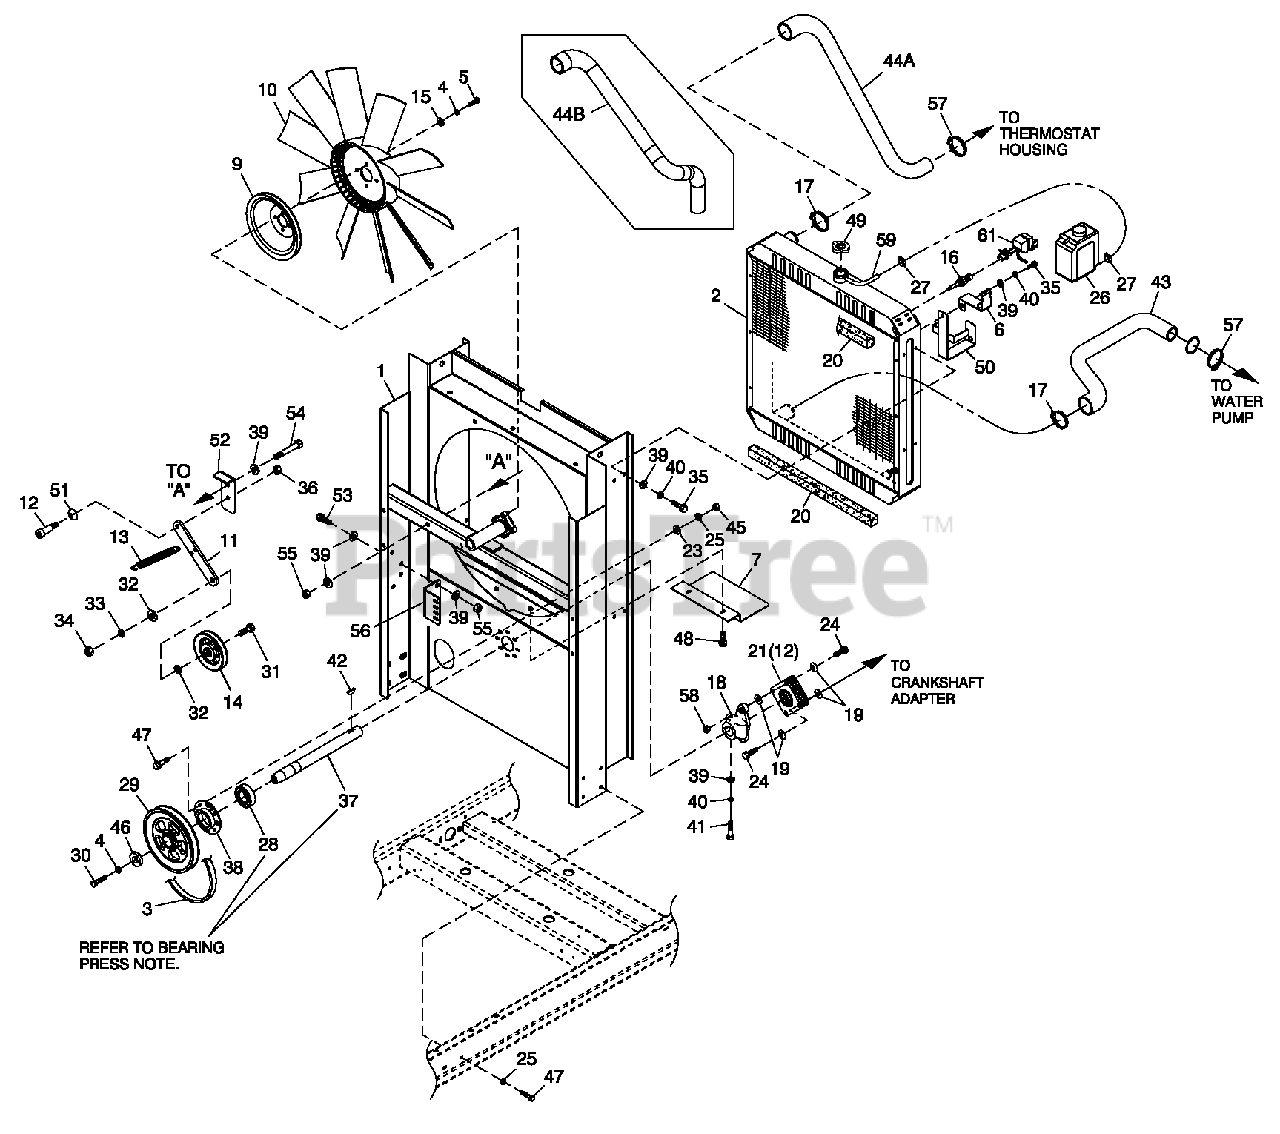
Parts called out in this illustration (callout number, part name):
1	WELDMENT RADIATORSUPPORTC2
2	RADIATOR 598 X 568 X 49 CPL RH
3	V-BELT 31/64" X 57-3/8"
4	WASHERLOCK M10
5	SCREW HHC M10-1.5X30 G10.9
6	BRACKET, SIGNAL CONDITIONER (USEDONLY WITH QTAPRODUCT)
7	SHIELD RADIATOR C4
9	PULLEY FANV-GROOVE9"
10	FAN COOL 22" DIA10 BLADE LH
11	FLATTENSIONERARM
12	SHOULDER BOLT 3/8X 1/2"
13	SPRING TENSION CPL
14	PULLEY V- BELT 4" FLANGED
15	WASHERFLAT 3/8-M10ZINC
16	PROBE COOLANT LEVEL 3/8NPTF (USE WITH HARNESS P/N 0G 4882)
17	CLAMP HOSE #28 1.32-225
18	HUBFLEXPLATE
19	WASHER FLEX (THIN)
20	TAPE FOAM 1 X 1 (26.75"LG)
21	DISK FLEX
23	WASHERFLAT 1/4-M6ZINC
24	SCREWHHC 5/16-24X1.124
25	WASHER LOCKM6-1/4
26	TANK COOLANT RECOVERY
27	CLAMP HOSE BAND 1/4
28	BEARING #6205 2NSE C3ESR2 S
29	PULLEY 4.5" DIA MACHINED
30	SCREW HHC M10-1.5X 30 G8.8
31	SCREWHHC 1/2-13X2" G8
32	WASHERFLAT 1/2 ZINC
33	WASHER LOCK 1/2
34	NUT HEX 1/2-13 STEEL
35	SCREW HHFCM8-125 X20WM6
36	NUT HEX LOCK 5/16-18 NY INS SS
37	SHAFT FAN DRVE
38	RETAINER BEARING
39	WASHERFLAT 5/16-M8ZINC
40	WASHER LOCKM8-5/16
41	SCREW HHC M8-1.25X 45 C8.8
42	KEY WOODRUFF 4X 19D
43	HOSE LOWER RADIATOR G2
44A	HOSE UPPER RADIATOR G2
44B	HOSE UPPER RADIATOR G2
45	NUT HEX M6X 1.0 G8 YEL CHR
46	SPACER .5X 1.5 X .25STL/ZINC
47	SCREW HHFCM6-10 X 2 0 G8.8
48	SCREW THF M6-1 X 16 N WAZ/JS
49	CAP RADIATOR 13 PSI
50	BRACKET COOLANT TANK
51	WASHER BELLEVILLE .75X.38X.028
52	TENS ION ER ARM SUPPORT BENT 90
53	SCREW HHC M8-1.25 X 20 C8.8
54	SCREW HHC M8-1.25 X 75 C8.8
55	NUT HEX LOCK M8-1.25 NY INS
56	BRACKET TENSIONERSPRING
57	CLAMP HOSE #24 B1.06-2.00
58	NUT HEX LOCK 5/16-24 NY INS
59	HOSE 9/32 ID(27"LG)
61	ASSY PCB LCL SENSOR (USE WITH I/N 16, P/N QH18270NLY)
